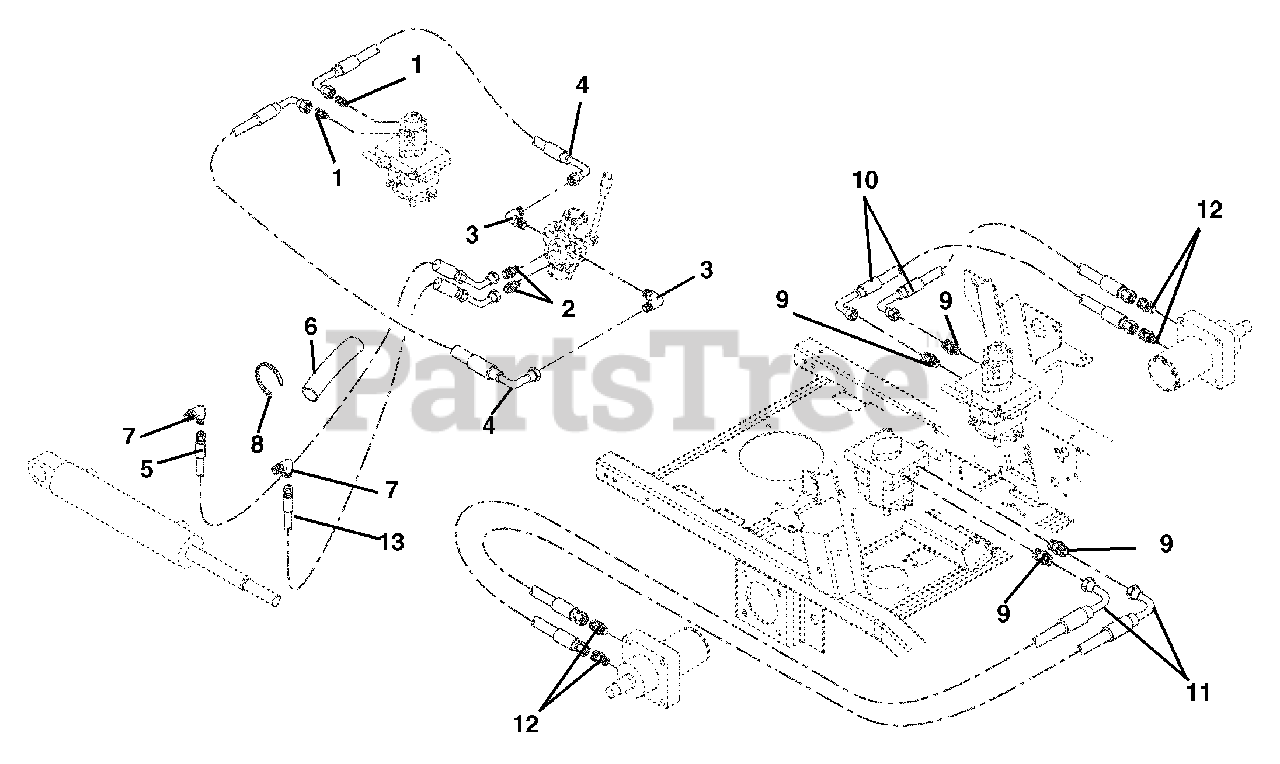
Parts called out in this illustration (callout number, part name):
1	FITTING, HYD (4 F5OLO)
2	FITTING, HYD (4-6 F5OLO)
3	FTG, HYD ELBOW M4F-M8O
4	HOSE,HYD .25-17-2K F04F9-F04F9
5	HOSE,HYD .25-47-2K F04F0-F04F4
6	SLEEVE, PROTECTIVE
7	FITTING, HYD (4 C5OLO)
8	CABLE TIE LG 5-1/2
9	ADPTR,FACE SEAL 8X8 1/2 O-RING
10	HOSE,HYD .50-19-2K F08F9-F08F9
11	HOSE,HYD .50-20-2K F08F0-F08F0
12	FTG, HYD STR M10O-M8F
13	HOSE,HYD.25-42-2K F04F0-F04F4
